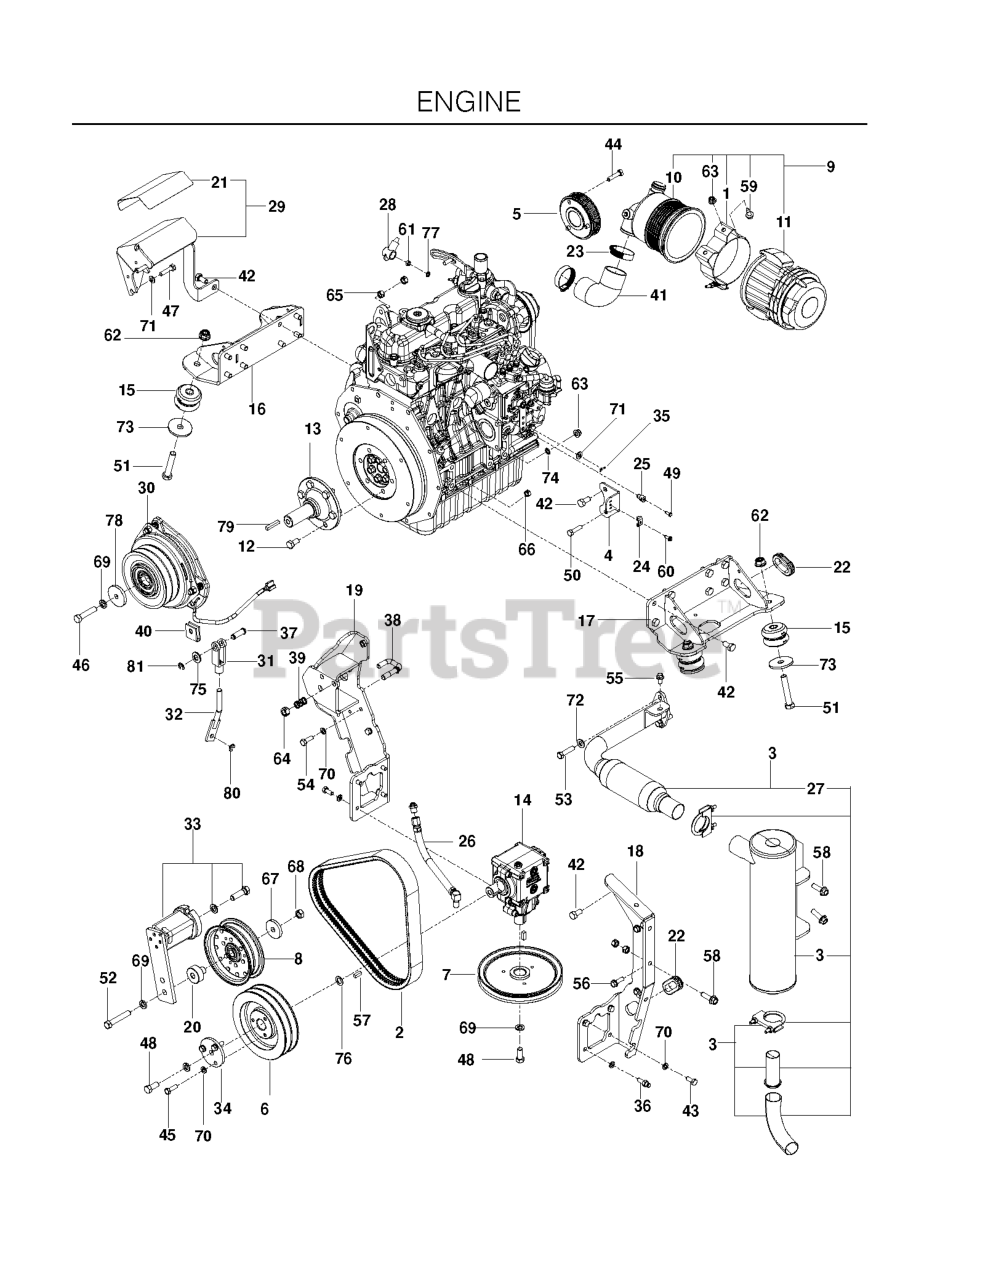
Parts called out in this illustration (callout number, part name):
1	MOUNTING BRACKET
2	BELT, CLUTCH
3	KIT.SPARK.ARRESTER
4	BRACKET, THROTTLE
5	PULLEY, CRANK
6	PULLEY, GEAR BOX
7	PULLEY, DRIVE, DECK
8	IDLER PULLEY
9	AIR FILTER ASSY - NON-TURBO
10	BODY - 90 DEG
11	PRECLEANER ASM
12	MUFFLER.DIESEL.KUBOTA
13	SHAFT, PILOT
14	GEAR BOX, 90 DEGREE
15	ISOLATOR, ENGINE
16	MOUNT, MOTOR, LT - BLK
17	MOUNT, MOTOR, RT - BLK
18	MOUNT, GEAR BOX, BLK
19	MOUNT, GEAR BOX, BLK
20	MOUNT, IDLER
21	SHIELD, HEAT BARRIER
24	CLAMP, CABLE
25	SWIVEL, THROTTLE
26	HOSE, VENT
27	PIPE, MANIFOLD, DIESEL
28	TERMINAL COVER-SM
29	SHIELD, HEAT
30	CLUTCH, OGURA, DIESEL
31	YOKE, CLEVIS
32	LINKAGE, ANTI-ROTATION
33	TENSIONER, LOVEJOY, SE27
34	PLATE, PULLEY
35	COTTER PIN 3/32 X 1/2
36	PIN, PIVOT
37	PIN, 7/16 CLEVIS
38	PIN, DETENT
39	SPRING, COMPRESSION
40	SPACER, RUBBER
41	HOSE, AIR INTAKE
42	HCS M10-1.25 X 20 GR 8.8 ZD
43	SCREW 5/16C X 1 HEX CAP
44	HCS MB 1.25 X 35 GR 8.8 ZD
45	HCS 5/16C X 1
46	HCS 7/16-20 X 2 G8 ZN
47	HTB M8-1.125 X 25MM
48	SCREW 7/16-20 X 1 HHB GR5
49	HCS #10-24 X 1/2
50	HCS 5/16C X 1 1/4
51	HCS 1/2C X 2 3/4
52	HCS 7/16-20 X 2-3/4
53	HCS 3/8C X 1 1/2
54	M8X1.25X25 HHB GR8.8
55	SCREW M8X1.25X16 HHB GR 8.8
56	5/16-18X1 TAP SCREW
57	KEY 1/4 SQ X 3/4
58	HHFS 3/8-16 X 1.25 GD 5
59	BOLT 5/16-18 X 3/4
60	SCREW #10 X 1/2 SELF TAPPING
61	NUT M6 X 1.0 HEX
62	NUT, 1/2-13 HEX FLG NYLOC ZD
63	5/16-18 NYLOC FLANGE NUT
64	NUT 7/16C CENTERLOCK
65	NUT 3/8C CENTERBLOCK
66	NUT 5/16C CENTERLOCK
67	NUT, 7/16-20 HEX NYLOC ZC
68	SPINDLE WASHER
69	WASHER 7/16 LOCK
70	WASHER.LOCK.HVY.HLCL.SPR.5/16
71	FLAT WASHER 5/16 SAE
72	WASHER 3/8 SAE FLAT
73	WASHER, HEAVY
74	WASHER 5/16 EXT STAR
75	WASH 1/2 X 1 SPRG STL & NEOP
76	WASHER .515 X .874 X .031
77	WASHER 1/4 INT TOOTH
78	BLADE WASHER
79	KEY 1/4 SQ X 1-1/2
80	E RING 3/8"
81	RING, E, 7/16
